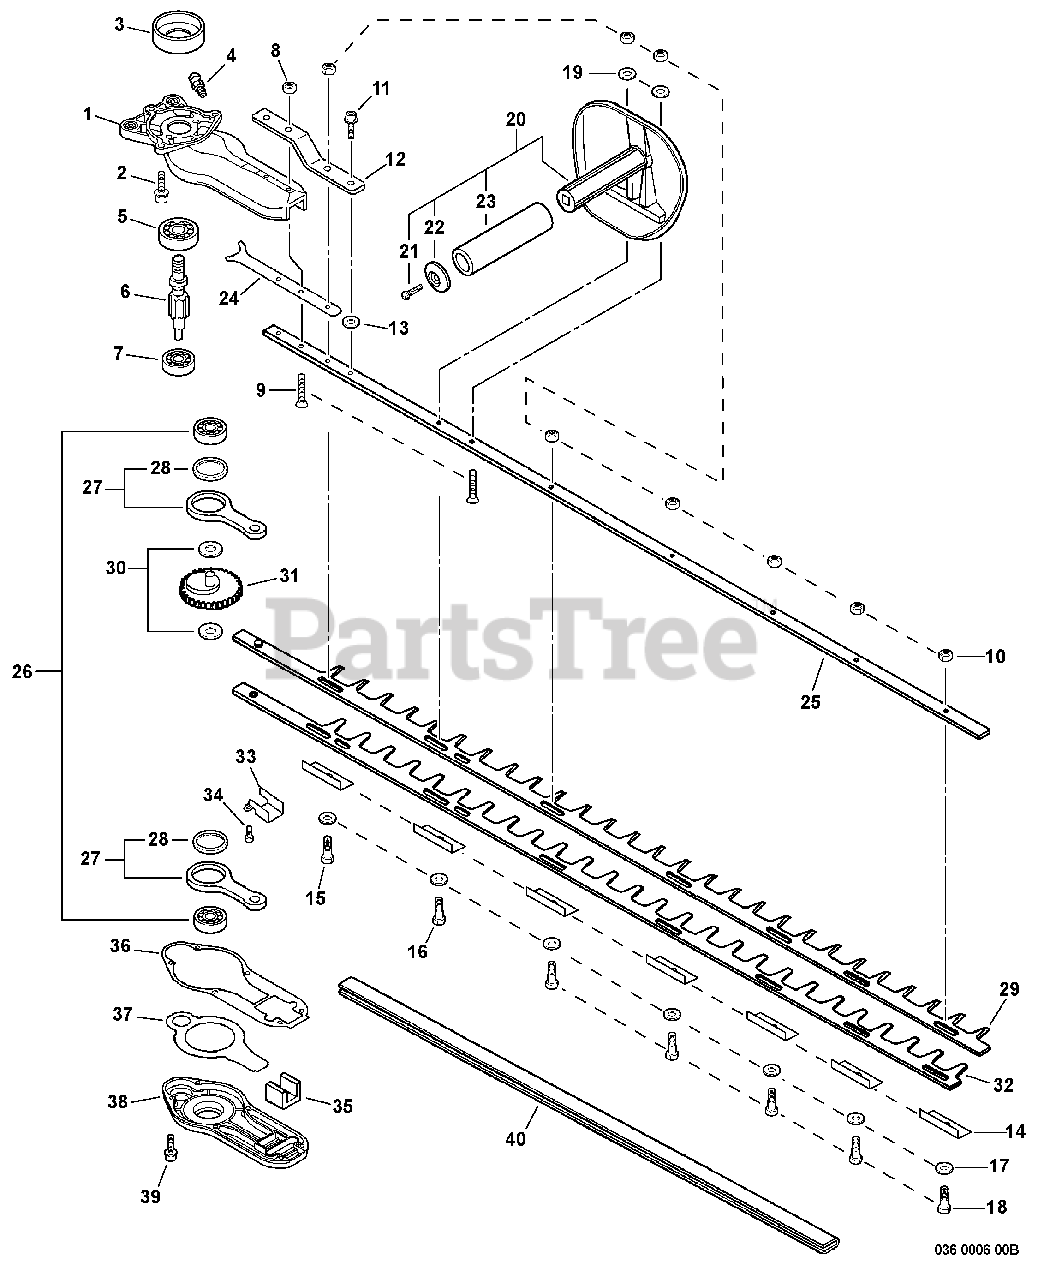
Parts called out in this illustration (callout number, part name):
1	CASE, GEAR - UPPER
2	BOLT 6×18
3	DRUM, CLUTCH
4	FITTING, GREASE
5	BEARING, BALL 6200
6	GEAR, SPUR
7	BEARING, BALL 608ZZ
8	NUT, FLANGE M6
9	BOLT 6×30
11	BOLT 6×12
12	BRACKET, BLADE
14	GUIDE, BLADE
15	BOLT 6×35
16	BOLT 6×40
18	BOLT 6×22
19	WASHER 6.5×13×1
20	HANDLE ASSY, FRONT
21	SCREW 5×14
23	GRIP, HANDLE
24	PLATE, EYE
25	SUPPORT, BLADE 40"
26	BEARING, BALL 6200
27	ROD, CONNECTING
28	BEARING, NEEDLE 30
29	BLADE, UPPER 40"
30	WASHER, THRUST 10
31	GEAR, SPUR
32	BLADE, LOWER 40"
33	GUIDE, BLADE
34	BOLT 4×16
36	GASKET, GEAR CASE
37	PLATE, GEAR CASE
38	COVER, GEAR CASE
39	BOLT 4×16
40	SCABBARD
